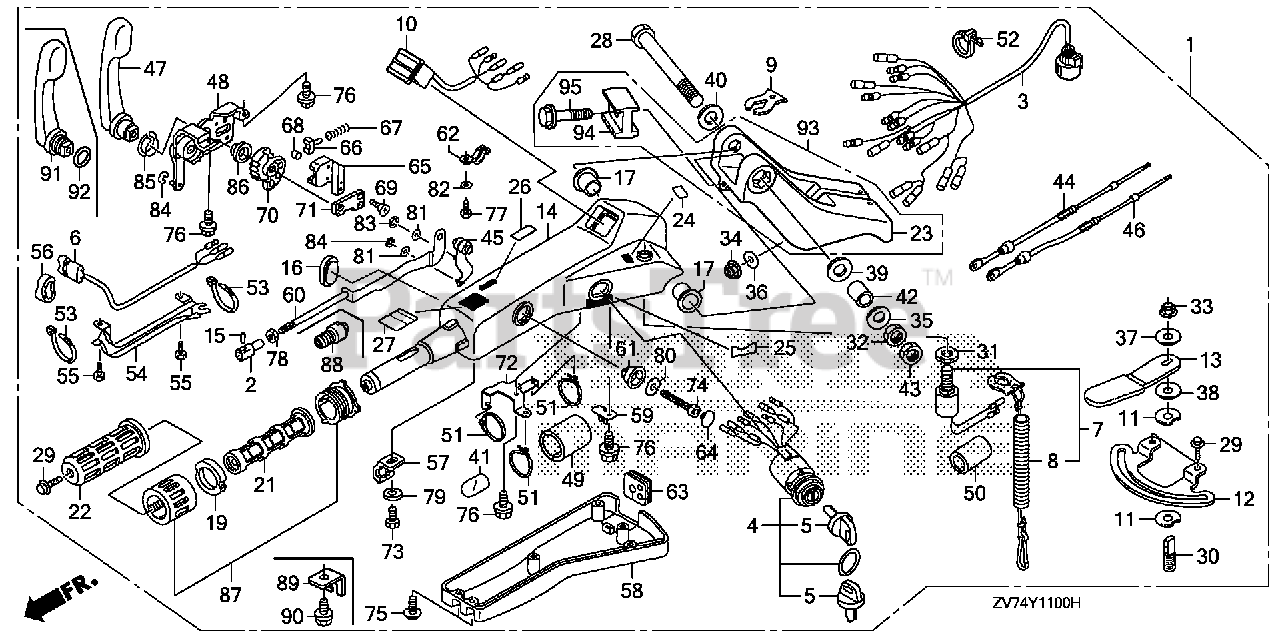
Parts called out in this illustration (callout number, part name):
1	HANDLEBAR KIT *NH282MU* (OYSTER SILVER METALLIC-U)
2	PIVOT, THROTTLE CABLE
3	CABLE ASSY., LONG HANDLE (A)
4	SWITCH ASSY., COMBINATION
5	KEY ASSY., COMBINATION SWITCH (35100-ZV5-003 ONLY)
7	SWITCH ASSY., EMERGENCY STOP
8	WIRE, EMERGENCY
9	CLIP, EMERGENCY LOCK
10	LAMP ASSY., INDICATION (2-LED)
11	BLOCK, FRICTION
12	PLATE, FRICTION
13	LEVER, FRICTION
14	HOUSING *NH282MU* (OYSTER SILVER METALLIC-U)
15	PIN, THROTTLE CABLE
16	GROMMET, POWER TILT SWITCH
17	BUSH, HANDLEBAR
18	GRIP ASSY., THROTTLE FRICTION
19	PAD, THROTTLE FRICTION
20	BLOCK, THROTTLE FRICTION
21	PIPE, GRIP
22	RUBBER, GRIP
23	BRACKET, STEERING *NH282MU* (OYSTER SILVER METALLIC-U)
24	MARK, EMERGENCY SWITCH INDICATION
24	MARK, EMERGENCY SWITCH INDICATION (EU)
25	MARK, STARTER (ENGLISH)
26	MARK, CHANGE
27	MARK, THROTTLE (ENGLISH)
28	BOLT, HEX. (12X80)
29	BOLT, FLANGE (6X12)
30	BOLT, STUD (8X26)
31	NUT, HEX. (16MM)
32	NUT, HEX. (12MM)
33	NUT, SELF-LOCK (8MM)
34	NUT, SELF-LOCK (10MM)
35	WASHER, WAVE (14MM)
36	WASHER (10MM)
37	WASHER (8MM)
38	WASHER, NYLON (8MM)
39	WASHER, PLAIN (12MM)
40	WASHER, PLAIN (12MM)
41	TUBE, CORD (30MM)
42	COLLAR, DISTANCE (12.2X23X16)
43	NUT, HEX. (12MM)
44	CABLE, THROTTLE
45	ARM, THROTTLE
46	CABLE, SHIFT
47	LEVER, SHIFT
48	FRAME ASSY., SHIFT
49	TUBE (38.1X40)
50	TUBE (19X40)
51	BAND (CONVEX CV-150)
52	BAND (CONVEX CV-200)
57	HOLDER, SWITCH
58	COVER, HANDLEBAR (LOWER)
59	BRACKET, CABLE
60	PLATE ASSY., LOCK
61	STOPPER
62	PLATE, GUIDE
63	GROMMET
64	CAP
65	GUIDE, SPRING
66	ACTUATOR
67	SPRING, COIL
68	ROLLER
69	SCREW (M5X14)
70	GEAR, SHIFT
71	PLATE, BALL GUIDE
72	BRACKET
73	BOLT (M5X8)
74	BOLT (M8X50)
75	BOLT (M5X12)
76	BOLT (M6X12)
77	BOLT (M5X12)
78	NUT, HEX. (5MM)
79	WASHER (5MM)
80	WASHER (8MM)
81	WASHER (10MM)
82	WASHER (5MM)
83	E-RING
84	E-RING
85	BEARING
86	BEARING
87	GRIP ASSY., THROTTLE FRICTION
88	ROD, GROMMET
89	CLAMP, BRACKET
90	BOLT (M6X12)
91	LEVER, SHIFT
92	O-RING (20.6X1.9)
93	BRACKET KIT, STEERING *NH282MU* (OYSTER SILVER METALLIC-U)
94	BLOCK, HEIGHT ADJUSTER
95	BOLT, FLANGE (8X28)
